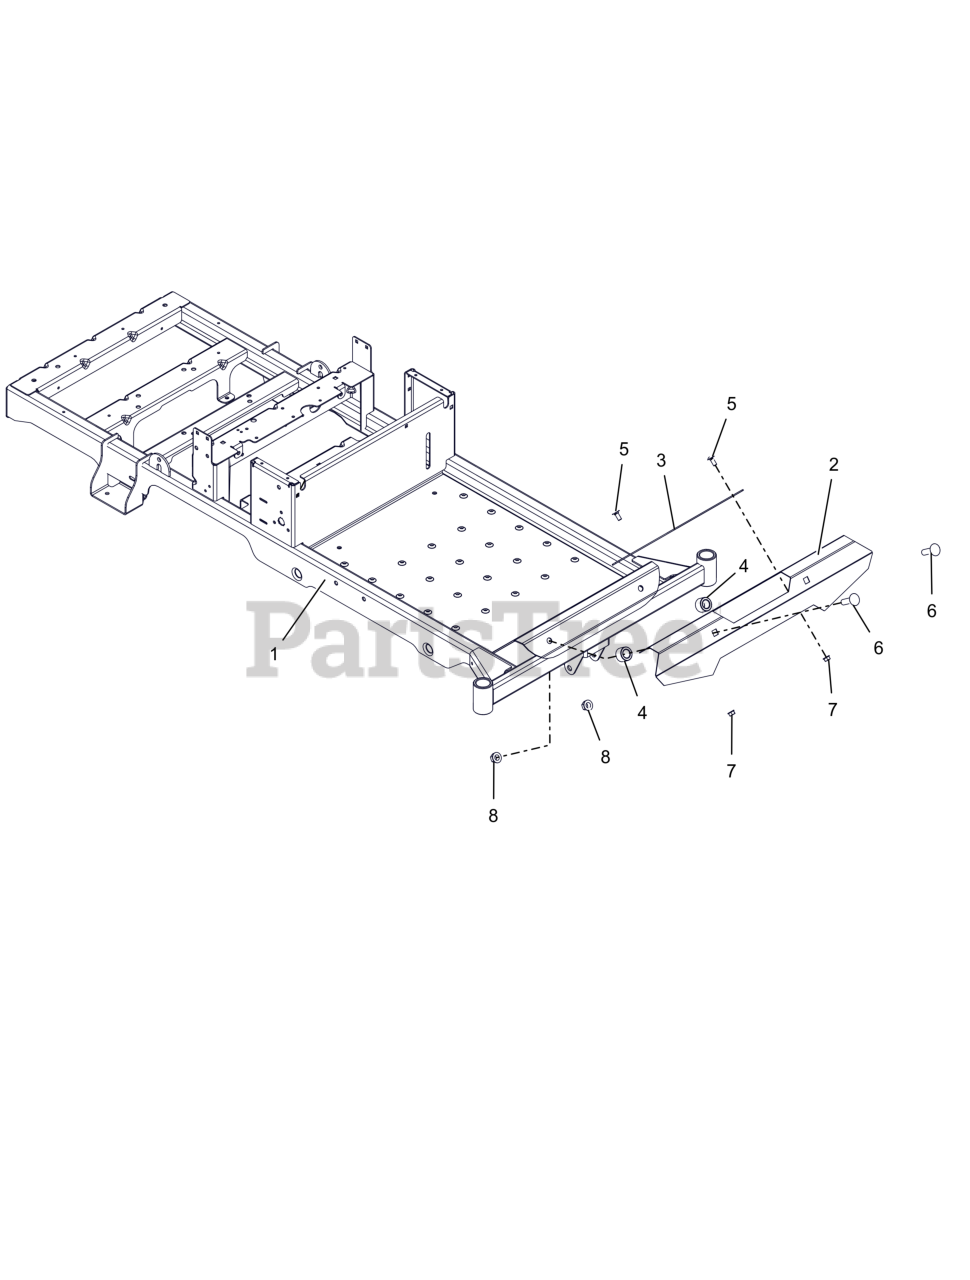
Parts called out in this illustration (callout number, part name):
1	KIT, EDGE FRAME W/DECALS
2	FOOTREST, (ORANGE)
3	GRIP, ADHESIVE (1" X 16" BLK)
4	TUBE, UPPER CONTROL PIVOT
5	BLT, RHSSN.31-18X.750 G5 ZCC
6	BLT,RHSN .50-13X1.75 G5 ZCC
7	NUT,LK-CTR-FLG .31-18 GF ZCC
8	NUT-LK-CTR-FLG .500-13 GG ZCC
